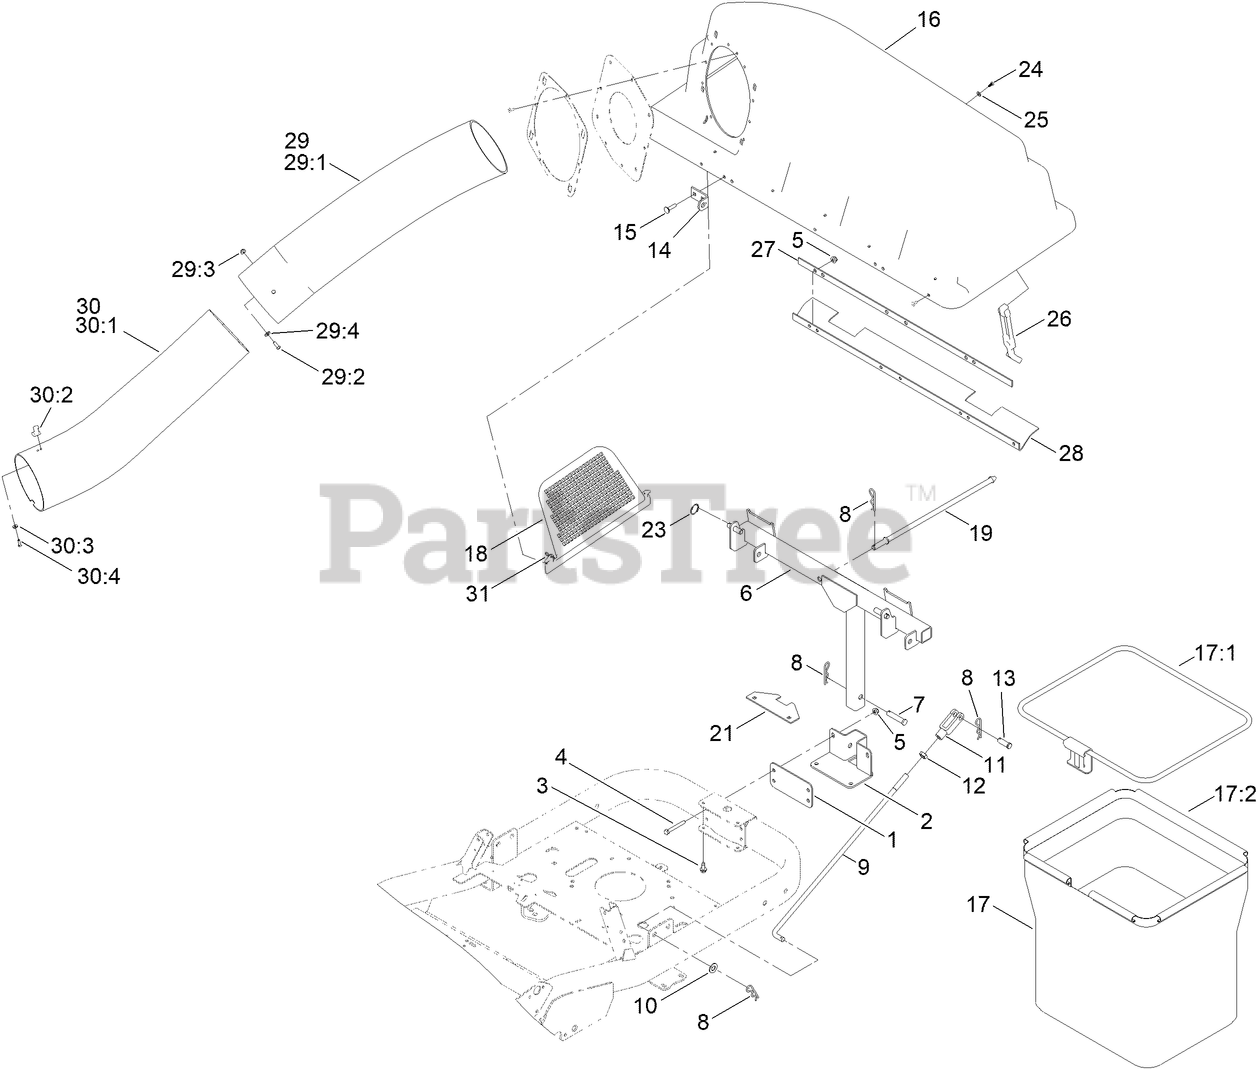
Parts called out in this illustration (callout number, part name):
2	SUPPORT-BAGGER
3	SCREW-HWHTF
4	SCREW-HH
5	NUT-HF, NI
6	PIVOT FRAME ASM
7	PIN-CLEVIS
8	PIN-HAIR
9	ROD-BAGGER
10	WASHER-FLAT
11	CLEVIS
12	NUT-JAM
13	PIN-CLEVIS
14	BRACKET-PIVOT, HOPPER
15	SCREW-CARR
16	BAGGER HOOD ASM
17	BAG ASM
17:1	FRAME, BAG [BLACK]
17:2	BAG ASM 20IN DEPTH
18	SCREEN-BAGGER
19	ROD-HOLD DOWN, HOOD
21	PLATE-SPACER
23	PIN-COTTER, CIRCULAR
24	SCREW-PLASTITE
25	WASHER-FLAT
26	LATCH-RUBBER
27	PLATE-BACKING
29	UPPER TUBE ASM
29:1	TUBE-UPPER
29:2	SCREW-HSBH
29:3	NUT-HF
29:4	WASHER-FLAT
30	LOWER TUBE ASM
30:1	TUBE-LOWER
30:2	LATCH-KEEPER
30:3	WASHER-FLAT
30:4	SCREW-PPH
